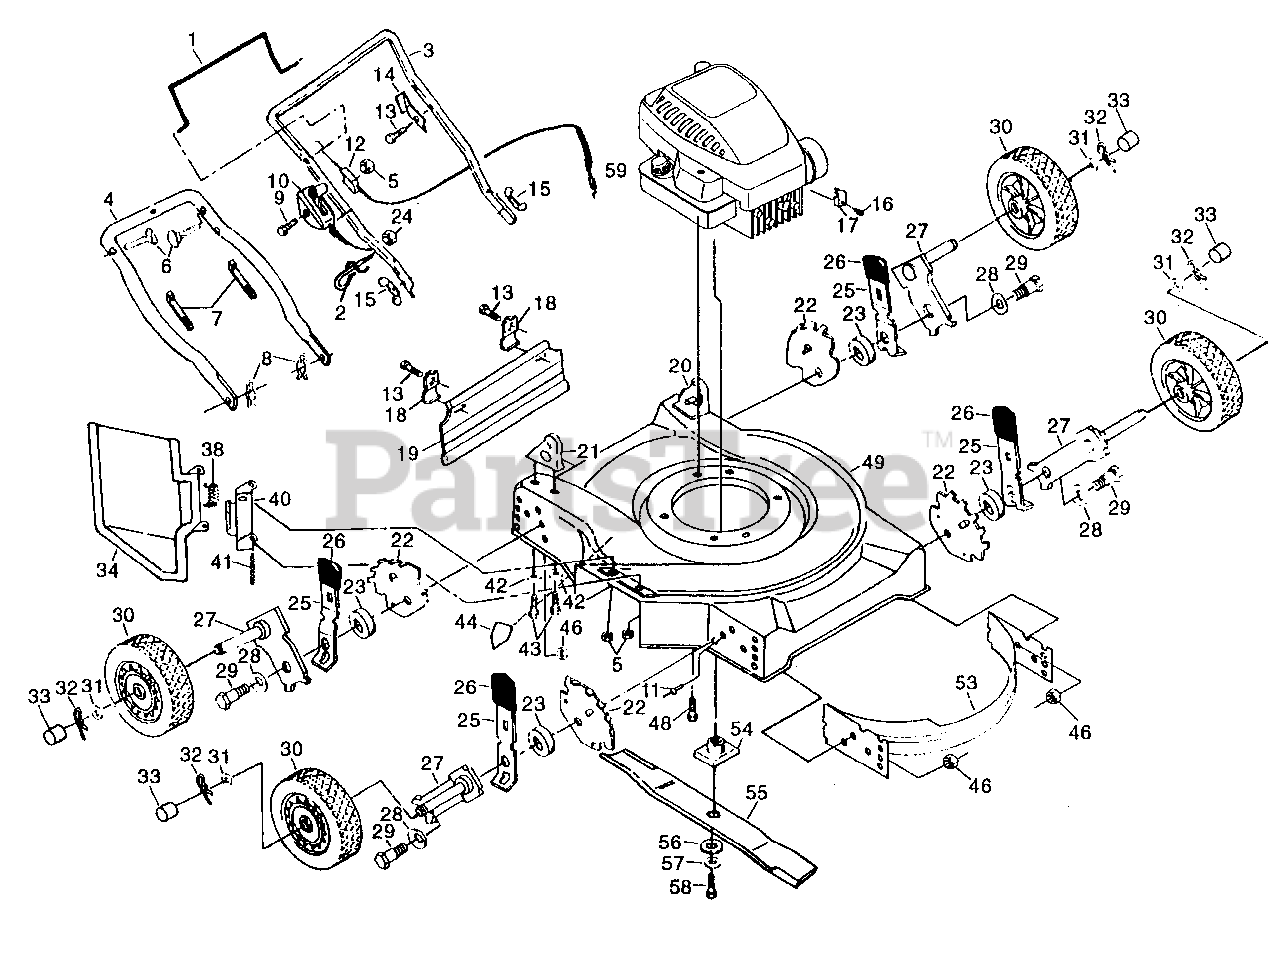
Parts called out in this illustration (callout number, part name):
1	Control Bar (AYP part number)
2	Rope Guide
3	Upper Handle (AYP part number)
4	Lower Handle (AYP part number)
5	Locknut (AYP part number)
6	Handle Bolt 5/16-18 x 1-3/4 (AYP part number)
7	Wire Tie (AYP part number)
8	Hairpin Cotter (AYP part number)
9	Hex Washer Head Screw 1/4-20 x 2-1/8 (AYP part number)
10	Throttle Control (AYP part number)
11	Pop Rivet (AYP part number)
12	Engine Zone Control Cable
13	Hex Washer Head Screw #10-24 x 1/2 (AYP part number)
14	Up-Stop Bracket (AYP part number)
15	Wing Nut (AYP part number)
16	Screw #10 x 5/8 (AYP part number)
17	Cable Clamp (AYP part number)
18	Skirt Bracket (AYP part number)
19	Rear Deflector (AYP part number)
20	Handle Bracket Assembly (Left) (AYP part number)
21	Handle Bracket Assembly (Right) (AYP part number)
22	Wheel Adjusting Bracket (AYP part number)
23	Spacer (AYP part number)
24	Keps Locknut 1/4-20 (AYP part number)
25	Selector Spring (AYP part number)
26	Selector Knob (AYP part number)
27	Axle Arm Assembly (AYP part number)
28	Belleville Washer (AYP part number)
29	Shoulder Bolt (AYP part number)
30	Wheel & Tire Assembly (AYP part number)
31	Washer (AYP part number)
32	Retainer Clip (AYP part number)
33	Hubcap (AYP part number)
34	Discharge Guard (AYP part number)
38	Torsion Spring (AYP part number)
40	Housing Bracket Assembly (AYP part number)
41	Hinge Rod (AYP part number)
42	Flat Washer (AYP part number)
43	Screw 5/16-18 x 3/4 (AYP part number)
44	Danger Decal (AYP part number)
46	Locknut 3/8-16 (AYP part number)
48	Hex Head Thread Rolling Screw 3/8-16 x 1 (AYP part number)
49	Mower Housing (Incl. Ref. #44)
54	Blade Adapter (AYP part number)
55	Blade 22" (AYP part number)
56	Hardened Washer (AYP part number)
57	Helical Lockwasher 3/8 (AYP part number)
58	Hex Head Screw 3/8-24 x 1-3/8 (Grd. 8)
59	Engine - Briggs & Stratton Model No. 10A902, Grass Catcher (AYP part number)
59	Engine - Briggs & Stratton Model No. 10A902, Mulcher Kit (AYP part number)
